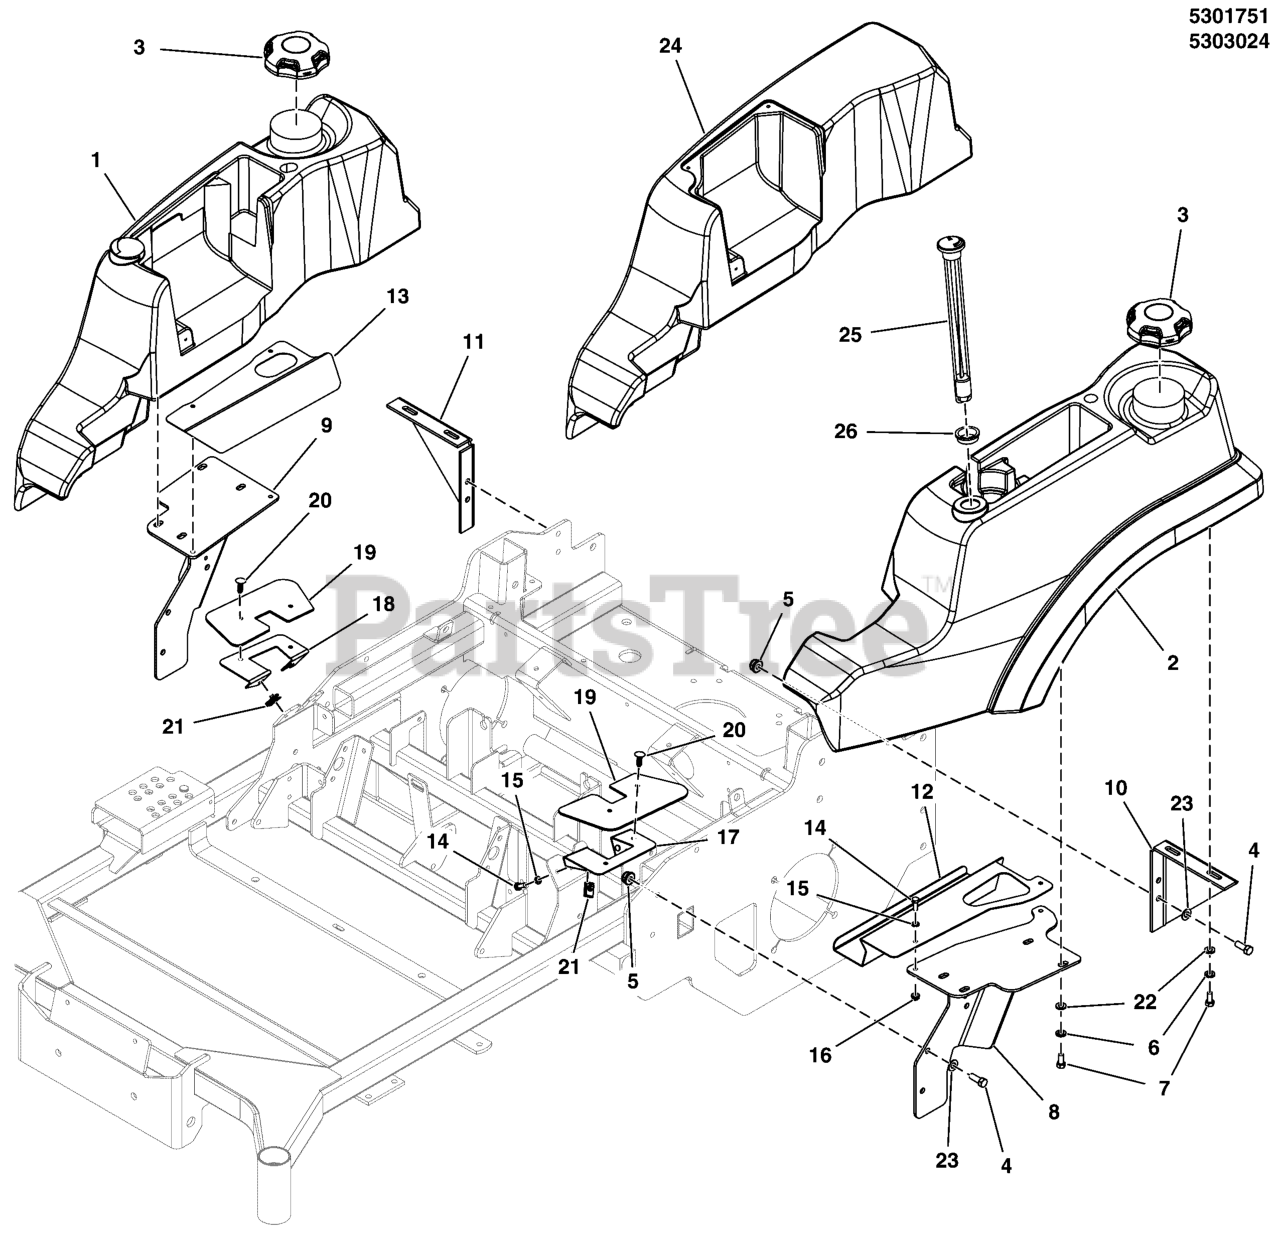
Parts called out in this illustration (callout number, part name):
1	TANK, FUEL, 5 GAL, SNP-PRO, RH, 2013
2	TANK, FUEL, 5.75 GAL, SNP-PRO, LH, 2013
3	FUEL CAP, 3-1/2", MANAGED VENT OUT, 12"
4	BOLT, 3/8-16 X 1" GD5 CZ
5	NUT, 3/8-16 HEX NYLOCK FLANGE
6	WASHER, 5/16 LOCK CZ
7	BOLT, 5/16-18 X 3/4 GD5
8	WELD, FUEL MOUNT, 200XT, LH - BLK
9	WELD, FUEL MOUNT, 200XT, RH - BLK
10	MOUNT, REAR TANK, LH - BLK
11	MOUNT, REAR TANK, RH - BLK
12	GUARD, SEAT, LH, S200XT - BLK
13	GUARD, SEAT, RH, F210Z - BLK
14	BOLT, 1/4-20 X 3/4 GD5 CZ
15	WASHER, 1/4 SAE
16	NUT, 1/4-20 HEX NYLOCK FLANGE
17	PLATE, FLAP MOUNTING, S200XT - LH - BLK
18	PLATE, FLAP MOUNTING, S200XT - RH - BLK
19	FLAP, CONTROL, S200XT
20	PUSH RIVET (TREE TYPE), BLACK
21	BODY CLIP, 1/4-20 X 1/2 DEEP
22	WASHER, 5/16 F436 FLAT
23	WASHER, 3/8 SAE
24	TANK, FENDER, SNP-PRO, RH, 2013
25	GAUGE, FUEL, 12
26	GROMMET, FUEL GAUGE
